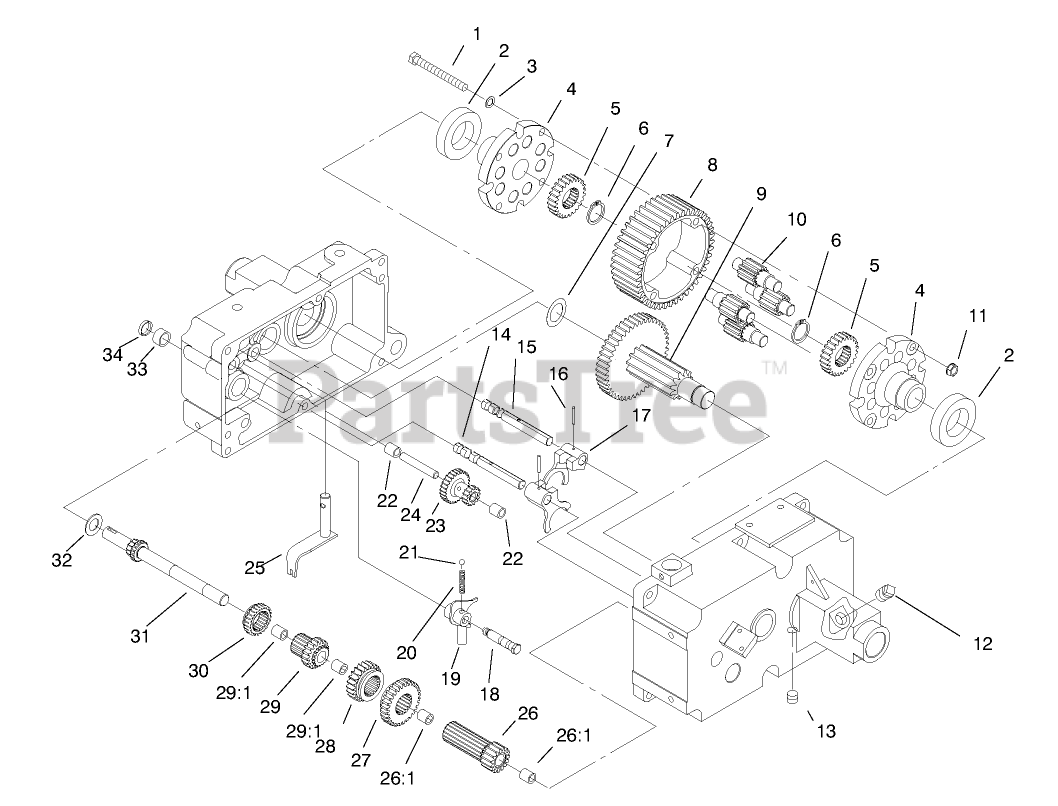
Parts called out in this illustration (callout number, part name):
2	BEARING-BALL
3	WASHER
4	END CAP-DIFFERENTIAL
5	GEAR-AXLE DIFFERENTIAL
6	RING-SNAP
7	WASHER-THRUST
8	GEAR-DIFFERENTIAL RING, 43T
9	GEAR ASM
10	GEAR-PINION, 11T
11	NUT-HEX
12	PLUG-PIPE, SQH
14	RAIL-SHIFT
15	RAIL-REAR SHIFT
16	PIN-ROLL
17	FORK-SHIFT
18	BOLT-DETENT
20	SPRING-SHIFT STOP
21	BALL-DETENT
22	BEARING-NEEDLE
24	GEAR-SHAFT REDUCTION
25	SHIFT ASM
25:1	Shift Lever
25:2	Shaft-Lever
26	GEAR
26:1	BEARING-NEEDLE
27	GEAR-LOW AND REVERSE
28	GEAR-HI AND 2ND
29	GEAR
29:1	BEARING-NEEDLE
30	GEAR-SLIDING
31	SHAFT-INPUT
32	WASHER-THRUST
33	BEARING-NEEDLE
34	SEAL-OIL
